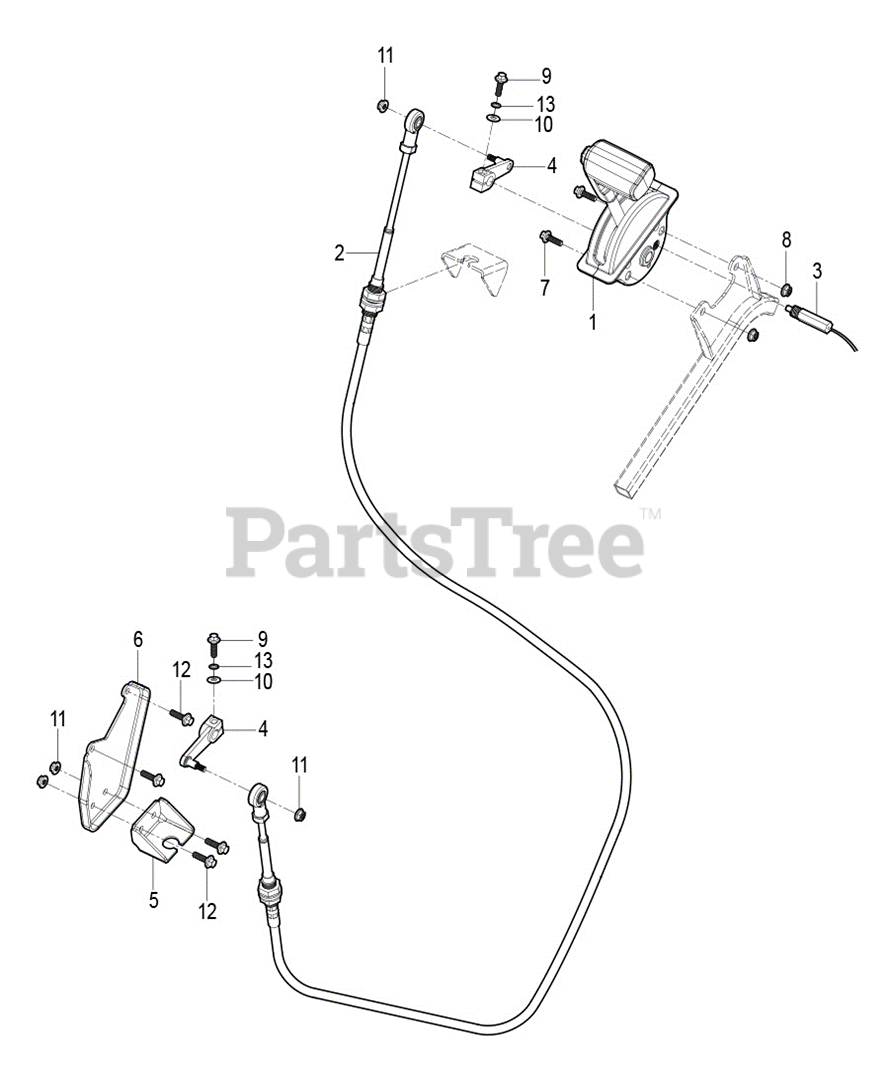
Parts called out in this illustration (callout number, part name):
1	GEAR SELECTOR
2	GEAR SELECTOR CABLE
3	REVERSE CONTROL CABLE
4	GEAR SELECTOR ARM
5	GEAR SELECTOR CABLE BRACKET
6	GEAR SELECTOR BRACKET
7	HEX HEAD FLANGE BOLT M8X50
8	LOCK NUT M8
9	HEXAGON FLANGE BOLT M6X25
10	FLAT WASHER
11	HEX FLANG NUT M6
12	HEXAGON FLANGE BOLT M6X16
13	SPRING WASHER
